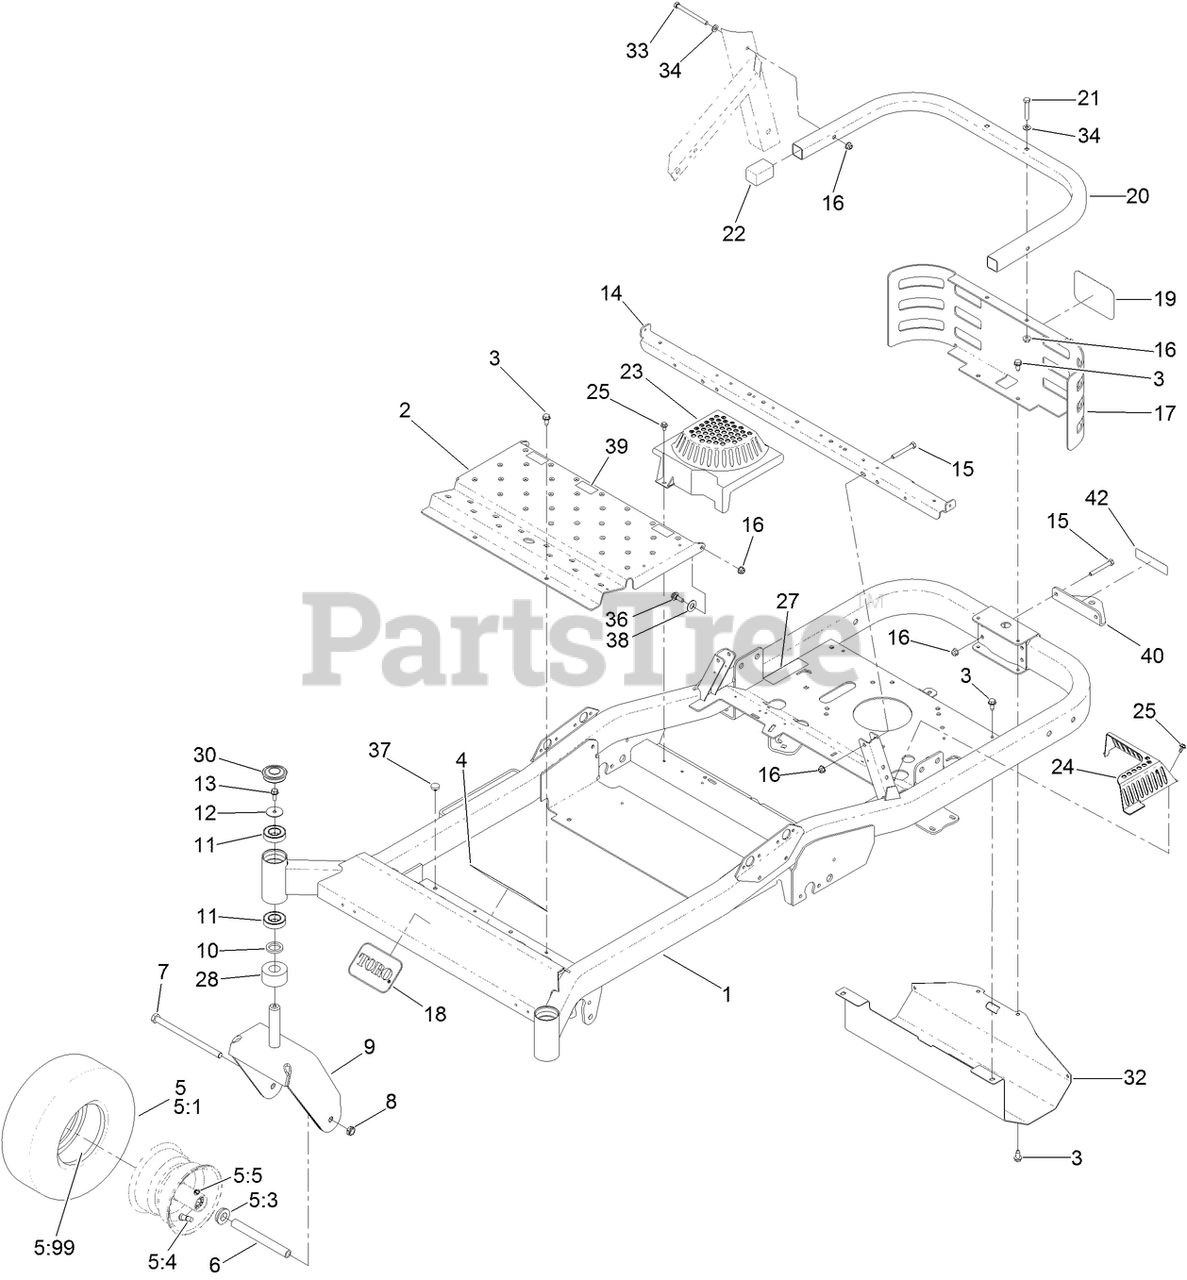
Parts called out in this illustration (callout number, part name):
1	FRAME ASM
2	PAN-FLOOR
3	SCREW-HWHTF
4	DECAL-DANGER
5	TIRE AND WHEEL ASM
5:1	TIRE-13 INCH SMOOTH
5:3	BUSHING-FLANGE
5:5	FITTING-GREASE
5:99	TUBE-INNER
6	SPANNER
7	SCREW-HH
8	NUT-HEX
9	FORK-CASTER
10	WASHER-THRUST
11	BEARING-BALL
12	WASHER-FLAT
13	SCREW-HHF
14	SUPPORT-SEAT
15	SCREW-HH
16	NUT-HF, NI
17	GUARD-REAR
18	DECAL
20	TUBE-GUARD
21	SCREW-HH
23	COVER-FAN, RH
24	COVER-FAN, LH
25	SCREW-HHFTF
27	DECAL-EMISSIONS
28	SPACER-CASTER
30	CAP-GREASE
32	SHIELD-HEAT
33	SCREW-HH
34	WASHER-PLAIN
36	SCREW-SHOULDER
37	BUMPER
38	WASHER-TEFLON
39	PAD-RUBBER
40	BRACKET-HITCH
